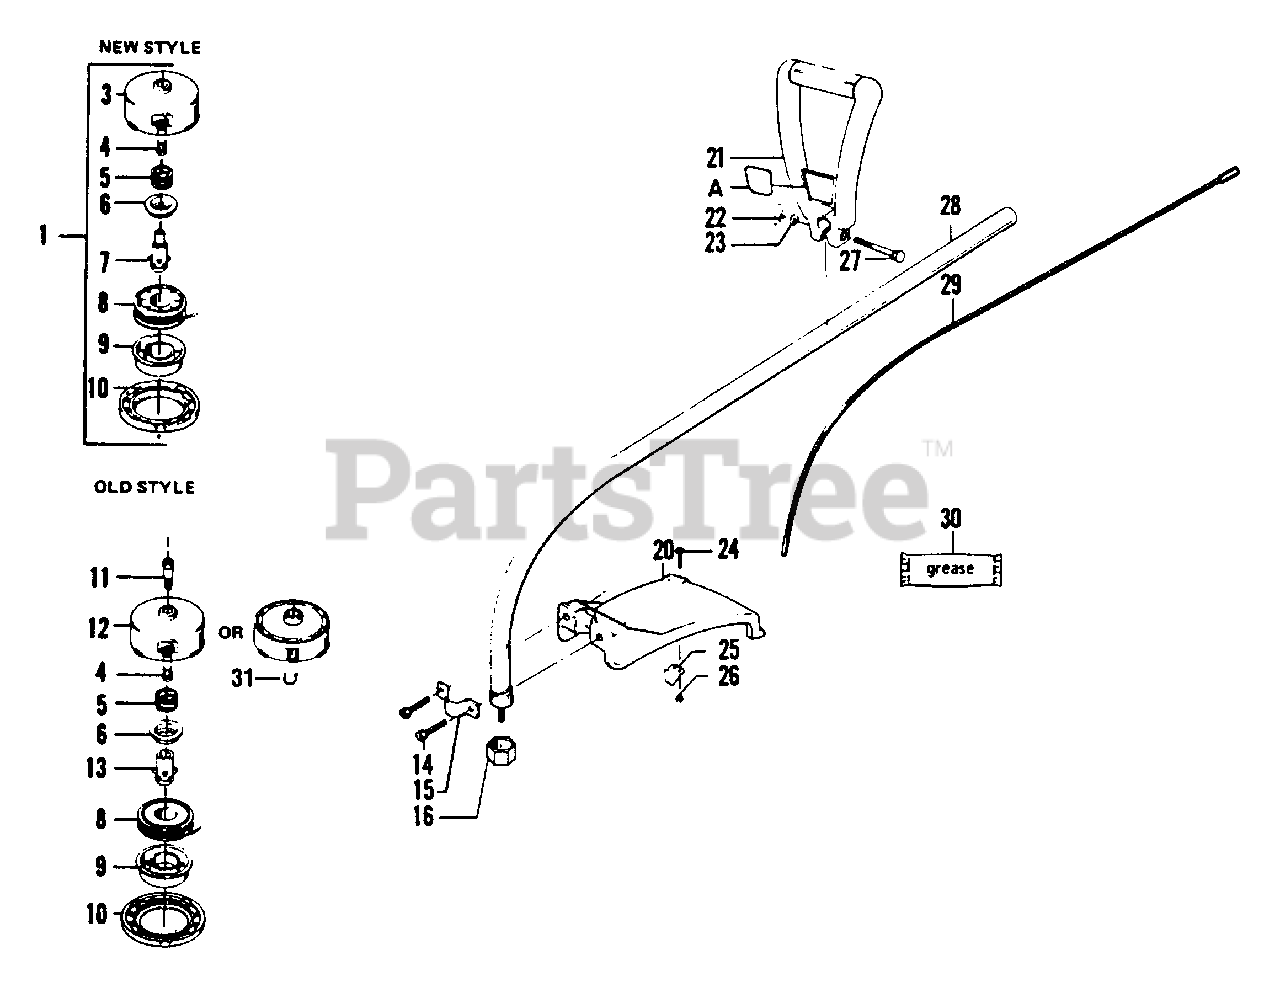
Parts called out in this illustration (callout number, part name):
1	Cutting Head Ass'y - New Style
3	Hub w/Line Saver
4	Line Saver
5	Spring
6	Adaptor - Spring
7	Drive Gear
8	Spool w/Line
9	Release Button
10	Cover
11	Bolt - Drive Adaptor - Old Style
12	Hub w/Line Saver - Old Style
13	Drive Gear - Old Style
14	Screw - Shield
15	Bracket - Shield (1/4 - 20 x 1-3/4)
16	Dust Cup
20	Shield
20	Shield Ass'y
21	Assist Handle
22	Wing Nut - 1/4 - 20
23	Washer - 1/4 Flat
24	Screw- Line Limiter (10- 24 x 1)
25	Limiter - Line
26	Nut - Line Limiter
27	Hex Bolt - 1/4 - 20 x 2-1/4
28	Drive Shaft Ass'y
29	Flexible Shaft Ass'y
30	Flex Shaft Lube
31	Line Saver - Old Style
A	Decal - "D" Handle Warning Decal
